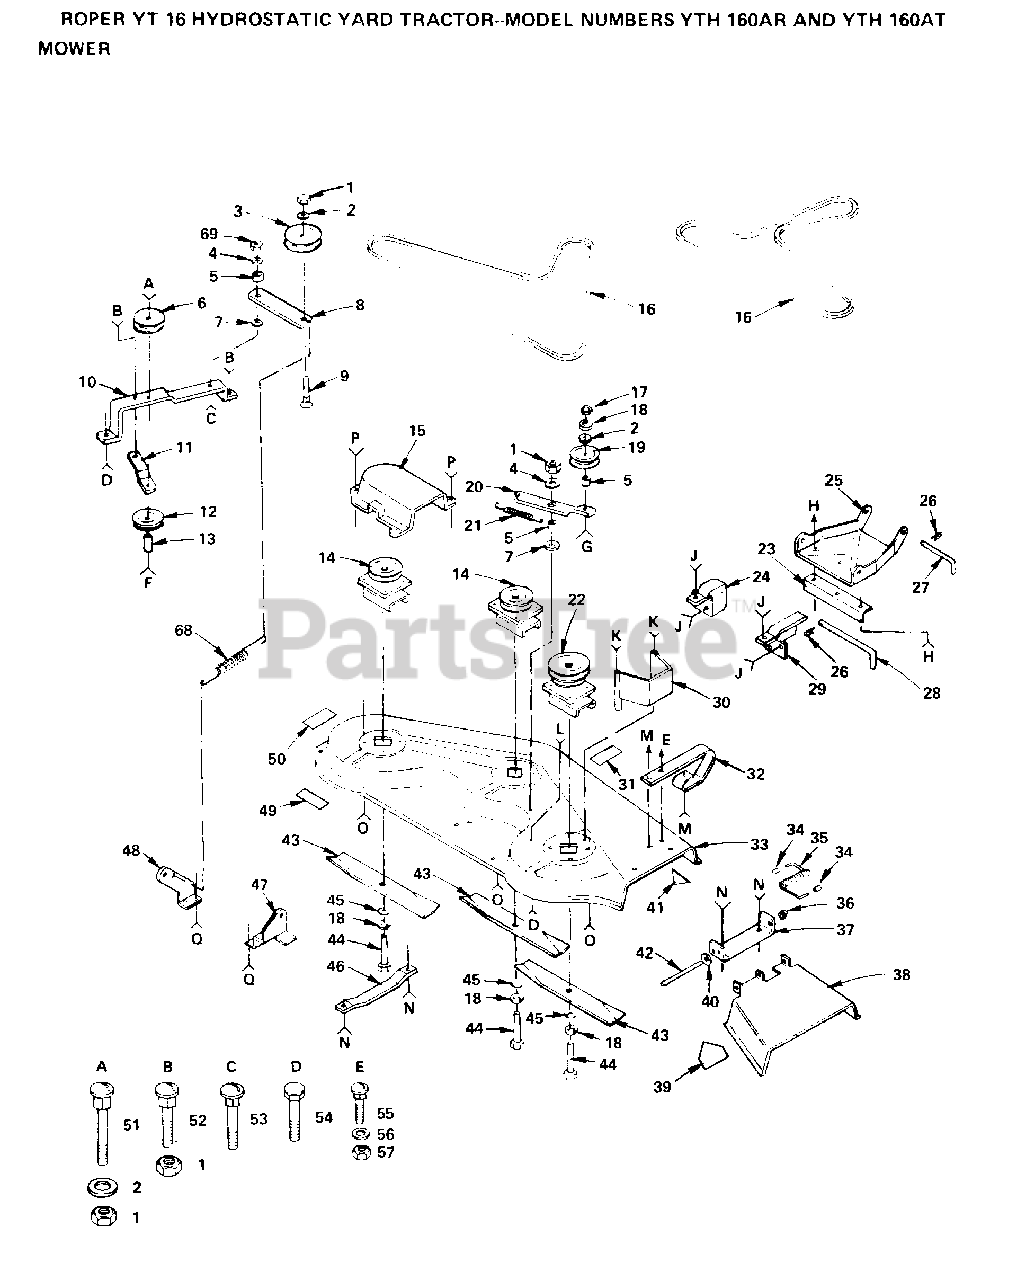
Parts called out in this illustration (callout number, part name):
2	WASHER
3	IDLER-FLAT T
5	SPACER RETAINER
6	IDLER-INSIDE T
7	"WASHER, WEAR LT"
8	ARM IDLER HYT
9	BOLT
10	"SUPPORT YT, BAR"
11	BRACE-IDLER YT
12	IDLER-FLAT YTV
15	GUARD YT
16	BELT-V.79.1.MWR
17	NUT.HEX.3/8-16UNC
18	LOCKWASHER
19	IDLER.FLAT.GTV
20	ARM-IDLER YT
21	SPRING YT
23	LINK STOP
24	BRACKET LH YT
25	LINK.PARALLEL
26	SPRING H
27	"ROD, FRT. PARAL T"
29	BRACKET RH YT
30	GUARD BELT HYT
31	DECAL.WARNING.T
34	CAP-SLEEVE LT
39	DECAL HYT
40	WASHER
41	DECAL - SAFETY STANDARD
42	ROD-HINGE T
44	BOLT.3/8-24X1-1/2
45	WASHER
46	RUNNER-LH M
49	DECAL HYT
50	DECAL-INST YT
51	BOLT.3/8-14X1.25
53	BOLT
55	BOLT
56	WASHER
68	"SPRING.EXT.8.5"""
69	LOCKNUT
